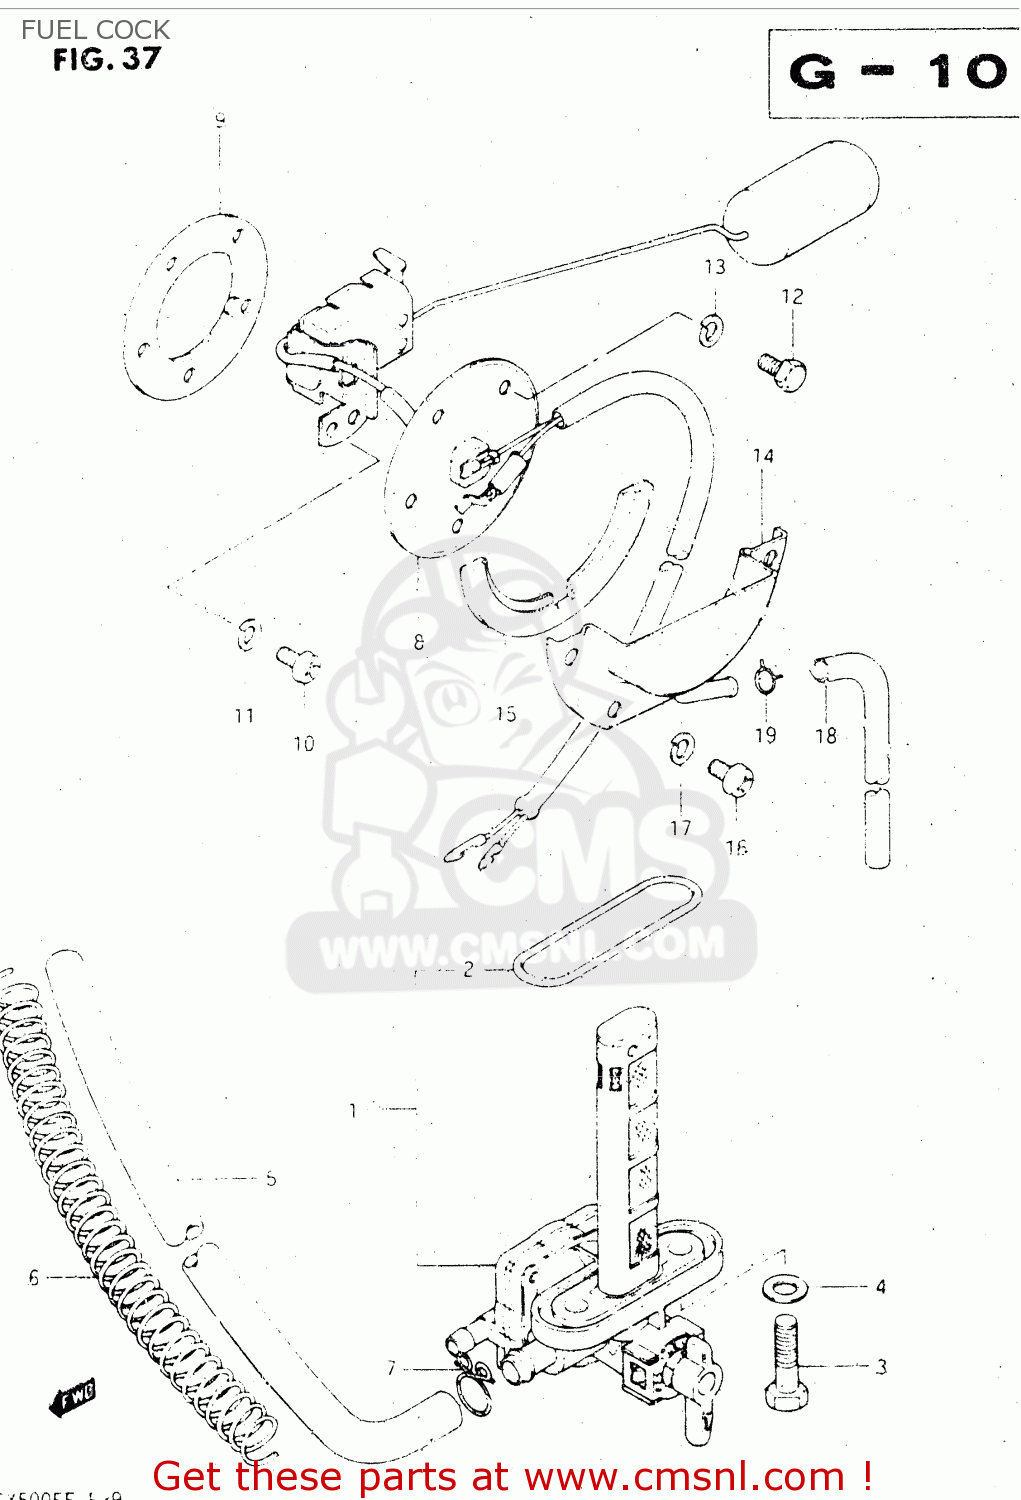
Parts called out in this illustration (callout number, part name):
1	COCK ASSY,FUEL
2	O RING
3	BOLT(6X20)
4	GASKET
5	HOSE
6	SPRING
7	CLIP
8	GAUGE ASSEMBLY,FUEL LEVEL
9	GASKET,FUEL LEVEL GAUGE (NAS)
10	SCREW 5X10
11	LOCK WASHER
12	BOLT 5X10
13	LOCK WASHER
14	PLATE,FUEL DRAIN
15	GASKET (NAS)
16	SCREW
17	LOCK WASHER
18	HOSE,FUEL
19	CLIP
